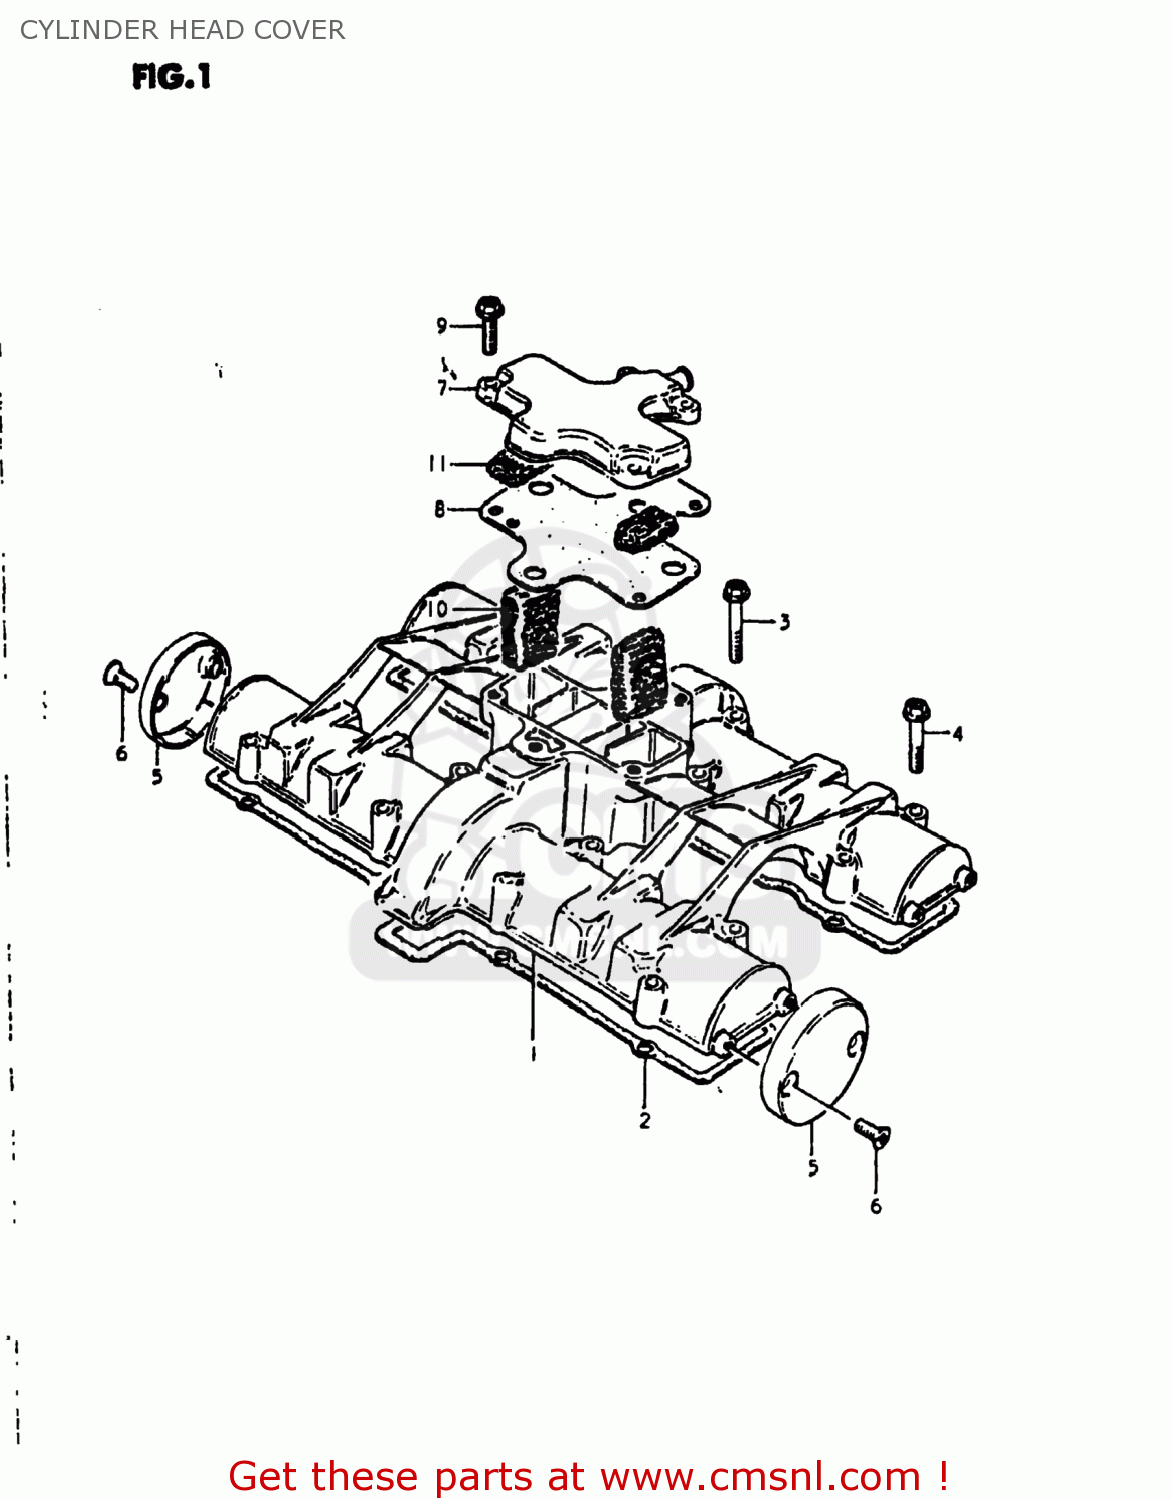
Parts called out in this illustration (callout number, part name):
1	COVER,CYLINDER HEAD
2	GASKET,CYLINDER HEAD COVER (MCA)
3	BOLT
4	BOLT 6X35
5	CAP,CYLINDER HEAD COVER
6	SCREW 5X12
7	COVER,BREATHER
8	GASKET (MCA)
9	BOLT
10	COVER,BREATHER
11	SEPARATOR,OIL BREATHER
